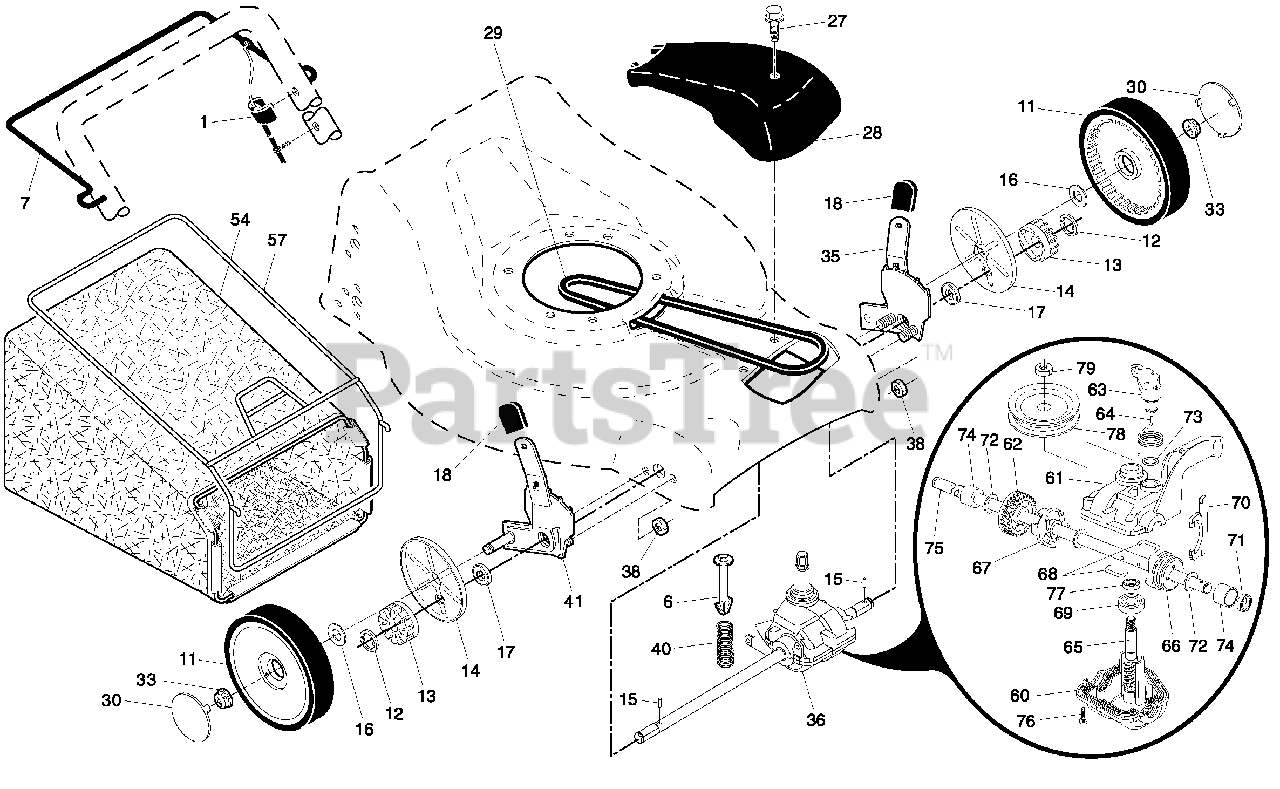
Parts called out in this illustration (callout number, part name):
1	Drive Control Assembly
6	Retainer, Spring
7	Bar, Drive Control
11	Wheel & Tire Assembly, Front, 8"
12	E-Ring
13	Pinion, Gear
14	Dust Cover
15	Pawl, Drive
16	Washer 1/2 x 1-1/2 x .134
17	Bearing, Wheel Adjuster
18	Selector Knob
27	Pan Head Tapping Screw #10-24 x 2-3/4
28	Drive Cover
29	V-Belt
30	Hubcap
33	Locknut
35	Kit, Wheel Adjuster, LH
36	Gear Case Assembly, Complete
38	Locknut 1/4-20
40	Spring
41	Kit, Wheel Adjuster, RH
54	Grassbag Assembly
57	Frame, Grassbag
60	Case, Lower
61	Case, Upper
62	Gear, 27 Teeth
63	Lever, Clutch
64	Spring, Return
65	Shaft, Input
66	Dog, Movable
67	Dog, Fixed
68	Wire, Formed
69	Bearing, Ball
70	Fork, Shift
71	Seal, Output Shaft
72	Washer
73	Seal, Case
74	Bushing
75	Shaft, Output
76	Screw
77	Seal, Input Shaft
78	Pulley, Drive
79	Locknut, Hex
